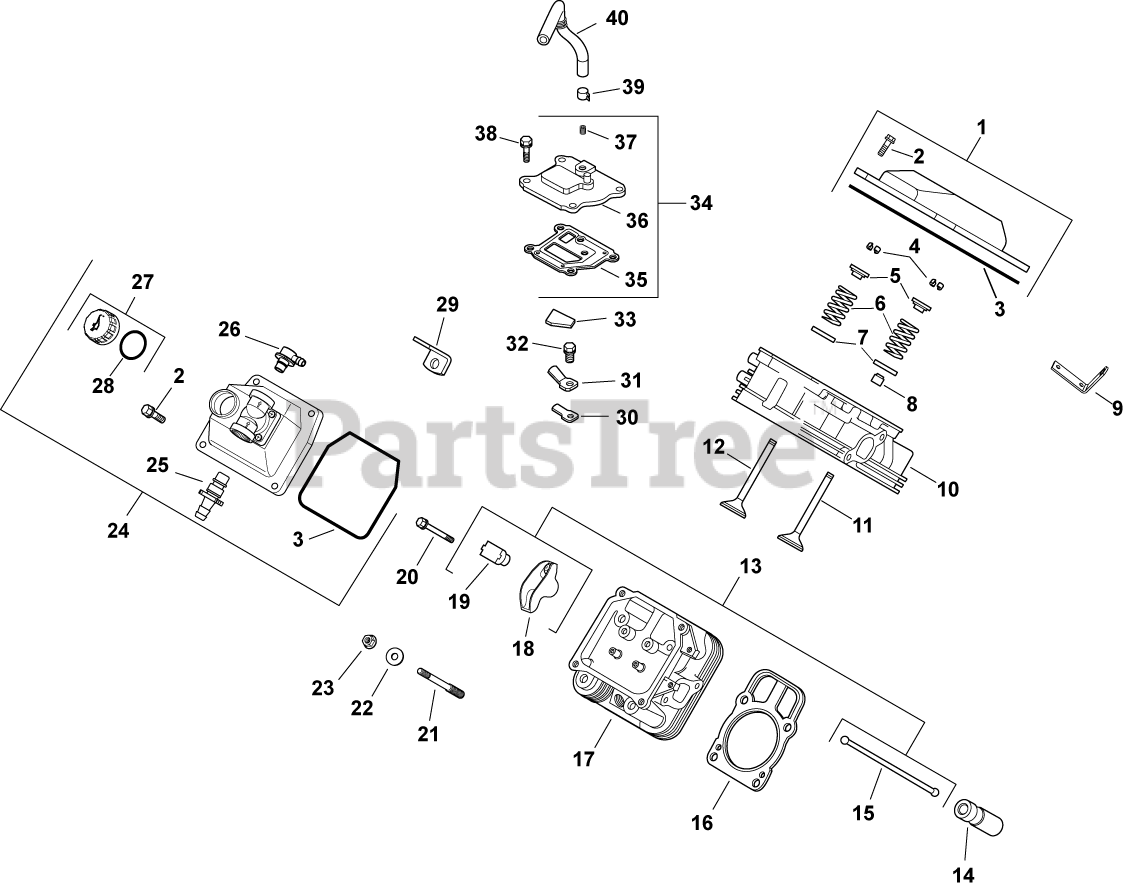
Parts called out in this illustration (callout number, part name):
1	KIT, VALVE COVER-PLAIN
2	SCREW, FLG M6X1.0X30
3	O-RING (YELLOW), VALVE COVER
4	KIT, RETAINER
5	RETAINER, VALVE SPRING - USE 25 173 28-S
6	SPRING, VALVE
7	RETAINER, SPRING
8	SEAL, VALVE STEM - (#2503214S)
10	HEAD, SERVICE ASSY CYL #1-USE 24 318 106
11	VALVE, INTAKE (STD)
12	VALVE, EXHAUST (STD) - USE 32 016 01-S
13	KIT, VALVE TRAIN
14	LIFTER, HYDRAULIC VALVE-USE 25 351 10-S
15	ROD, PUSH
16	CYL HEAD GASKET KIT-USE 24 841 04-S
17	HEAD, SERVICE ASSY CYL #2-USE 24 318 114
18	ARM, ROCKER
19	PIVOT, ROCKER ARM
20	SCREW, FLG M6X1.0X34
21	STUD, M8X1.25
22	WASHER, FLAT 8.6 MM
23	NUT, FLG M8X1.25
24	KIT, VALVE COVER-FUEL PUMP
25	KIT, STRAIGHT FITTING
26	KIT, 90 DEG. FITTING
27	CAP ASSY, OIL FILL (YELLOW)
28	O-RING-USE 24 153 32-S
29	STRAP, LIFTING-USE 25 445 03-S
30	REED, BREATHER
31	RETAINER, REED
32	SCREW, FLG THD FRM M5X.8X10
33	FILTER, BREATHER
34	KIT, BREATHER ASSEMBLY
35	GASKET, BREATHER-USE 24 041 67-S
36	COVER, BREATHER -USE 24 033 01-S
37	PLUG, CTSK PIPE 1/8"
38	SCREW,FLG THD FRM M6X1.0X20-(#25086396S)
39	CLAMP, BAND SPRING HOSE-(#2523737S)
40	HOSE, BREATHER
2401602-S	VALVE, EXHAUST (.25)
2401702-S	VALVE, INTAKE (.25)
